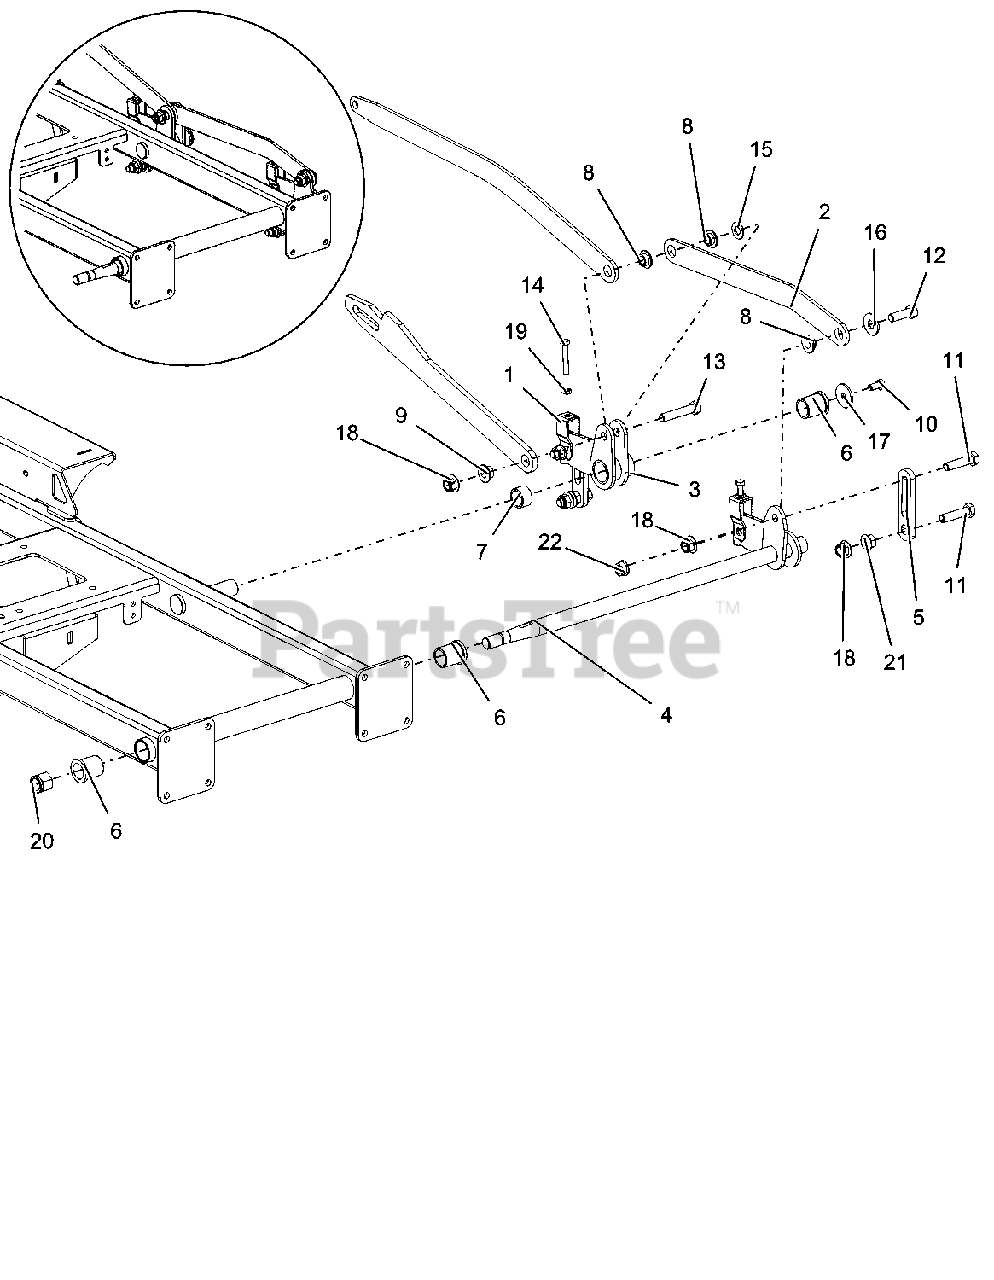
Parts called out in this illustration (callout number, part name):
1	BRKT, DECK LEVELING
2	PLATE, DECK ARM
3	WLDMT, REAR DECK ARM
4	WLDMT, FRONT LH DECK LIFT ARM
5	LINK-DECK LIFT - SHORT
6	BSHG-FLG 1.00X1.25X1.50X1.50
7	BUSH, SLV 1.00 X 1.25 X .75
8	BSHG, FLG .515X.750X.360X1.12
9	BSHG, FLG .515X.750X.480X1.12
10	@BLT-HEX .38-16X.75 GR5 YWZC
11	@BLT-HEX .50-13X2.00 GR5 YWZC
12	@BLT-HEX .50-13X1.50 GR5 YWZC
13	@BLT-HEX .50-13X2.50 GR5 YWZC
14	BLT-HEX .312-18X2.00 FTH GR5YZ
15	@WSHR-FL-STL.531X1.06X.095YWZC
16	@WSHR-FL-STL.563X1.38X.109YWZC
17	WSHR-FL-STL .380X1.50X.125YWZC
18	@NUT-LK-NYL-FLG .50-13 YWZC
19	NUT- JAM .312-18 YWZC
20	@NUT-LK-NYL .75-10 YWZC
21	NUT-SPNLK-FLG .50-13 YWZC
22	NUT-LK-CTR-FLG .50-13 YWZC
